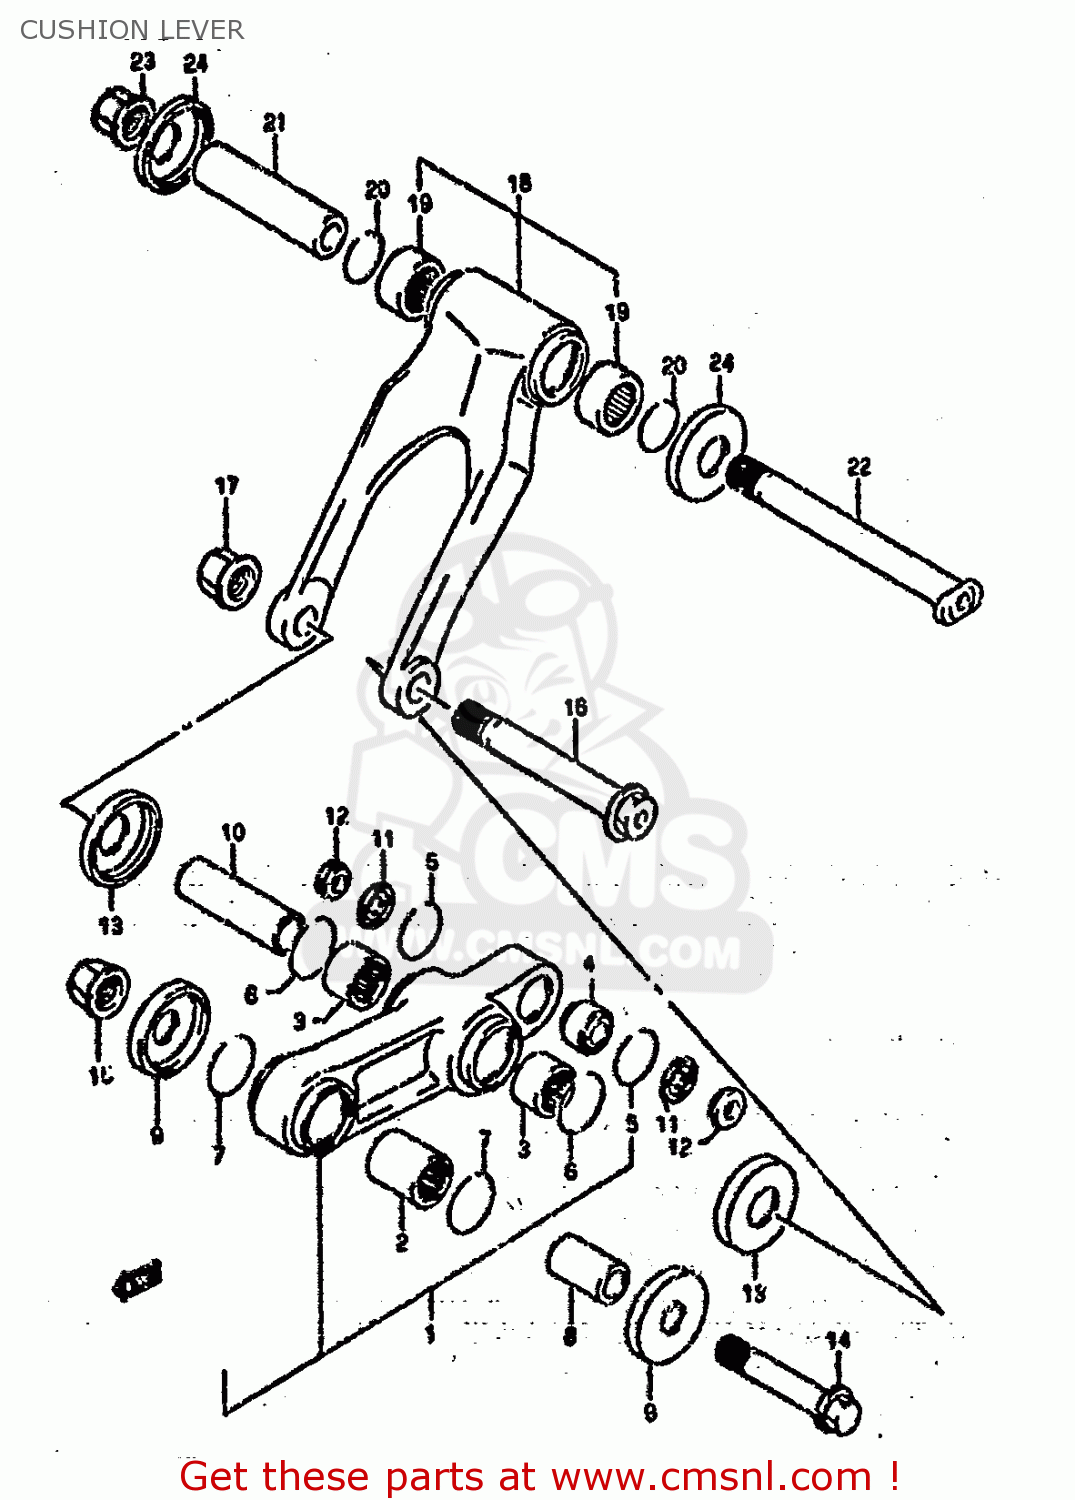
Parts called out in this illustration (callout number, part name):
1	LEVER SET,RR CUSHION
2	BEARING(20X27X25)
3	BEARING(22X28X20)
4	BEARING,RR CUSHION LEVER RR
5	RING,BEARING STOPPER
6	RING,STOPPER
7	RING,STOPPER
8	SPACER,RR CUSHION LEVER FR
9	SEAL,REAR CUSHION LEVER
10	SPACER,RR CUSHION LEVER CTR
11	SEAL,RR CUSHION LEVER RR DUST
12	SPACER,RR CUSHION LEVER RR
13	SEAL,RR CUSHION LEVER CTR
14	BOLT,RR CUSHION LEVER FR
15	NUT 12MM
16	BOLT,REAR CUSHION LEVER
17	NUT
18	ROD SET,RR CUSHION LEVER
19	BEARING(22X28X20)
20	RING,STOPPER
21	SPACER,RR CUSHION ROD
22	BOLT,RR CUSHION ROD
23	NUT
24	SEAL,RR CUSHION LEVER CTR
